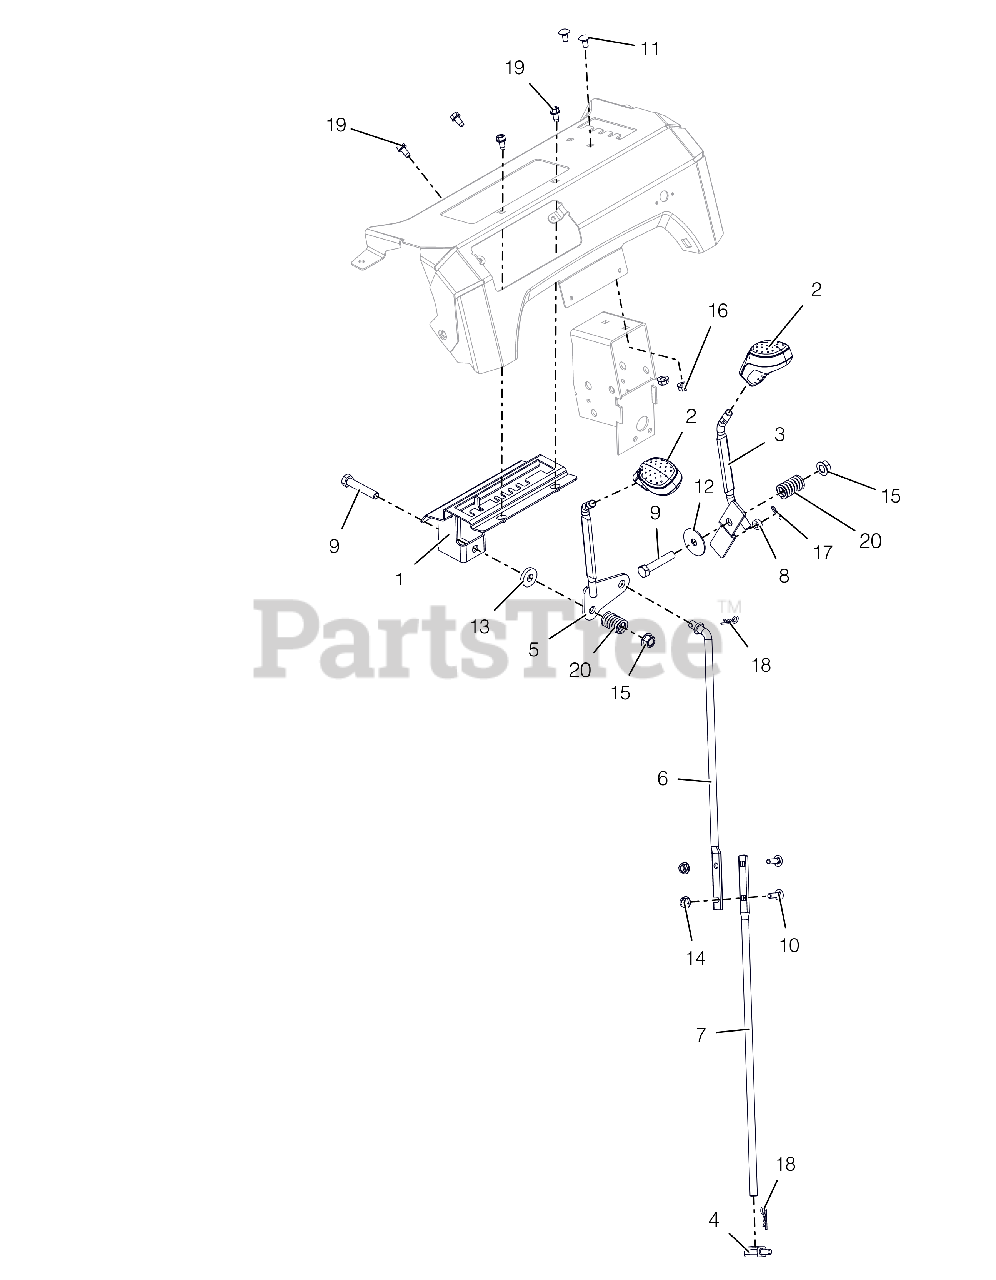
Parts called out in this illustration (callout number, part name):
1	WELDMENT, DETENT PLATE-COMPACT
2	KNOB, CONTROL, DASH
3	WELDMENT,SM DASH DEFL CONTROL
4	PIVOT,SHIFT ROD .375-16(TRUNN)
5	LEVER, CONTROL-SHIFT(WELDMENT)
6	ROD, SHIFT - UPPER
7	ROD, SHIFT-LOWER (SM DASH DLX)
8	BSHG-SLV .265X.500X.219
9	@BLT-HEX .38-16X2.00 GR5 YWZC
10	@BLT-RDHDSQNK .25-20X.75 G5YZ
11	@BLT-RDHDSQNK .25-20X.50 G5YZ
12	WSHR-FL-STL .380X1.50X.062 YWZ
13	WSHR-FL-STL .406X1.00X.188 YWZ
14	@NUT-LK-CTR-FLG .25-20 YWZC
15	@NUT-LK-TOP-FLG .38-16 YWZC
16	@NUT-LK-TOP-FLG .25-20 YWZC
17	PIN-HAIR INT .06X.18X.77
18	PIN-HAIR INT .08X.18X1.18 YWZC
19	SCR-TAP .25-20X.50 HWH TR YWZ
20	SG-COMP .125X.781X1.250
